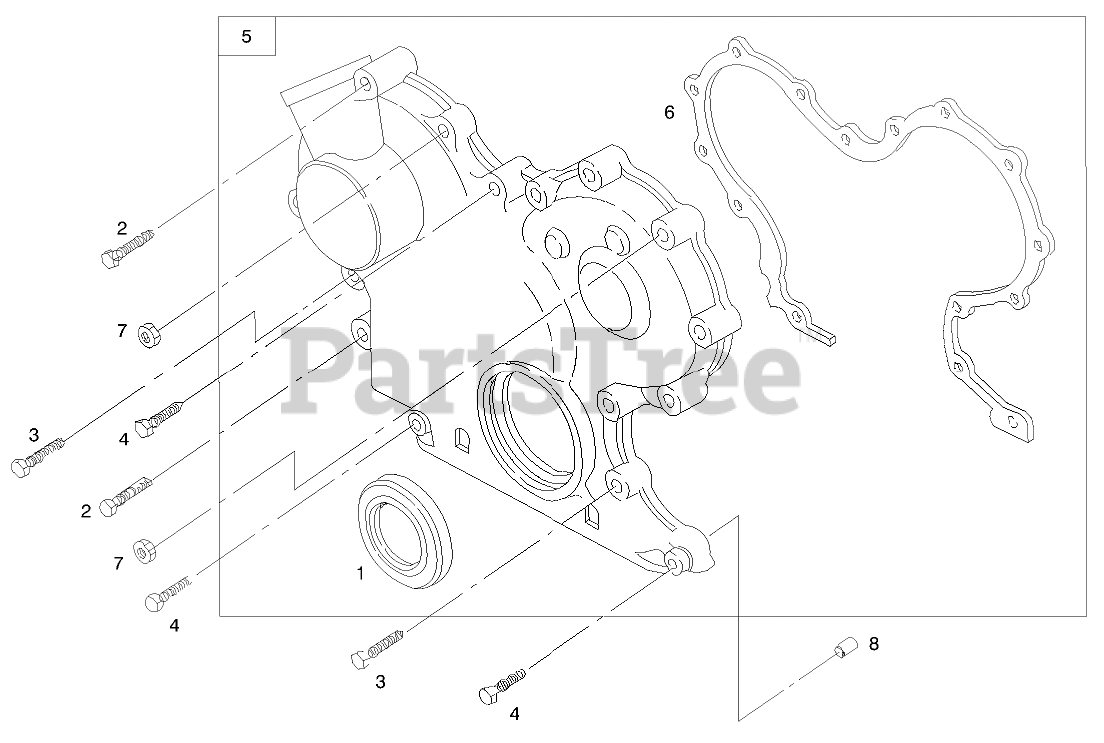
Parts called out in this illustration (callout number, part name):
1	SEAL-OIL
1	HEAD-CYLINDER
2	SCREW-HEX
3	SCREW-HEX
4	SCREW-HEX
5	GEAR COVER ASM
6	GASKET-COVER, GEAR
7	NUT-HEX, METRIC
8	PIN-LOCATING
8	SWITCH-TEMPERATURE, WATER
9	GASKET-SET
14	KIT-VALVE OVERHAUL
15	SHAFT-GEAR
